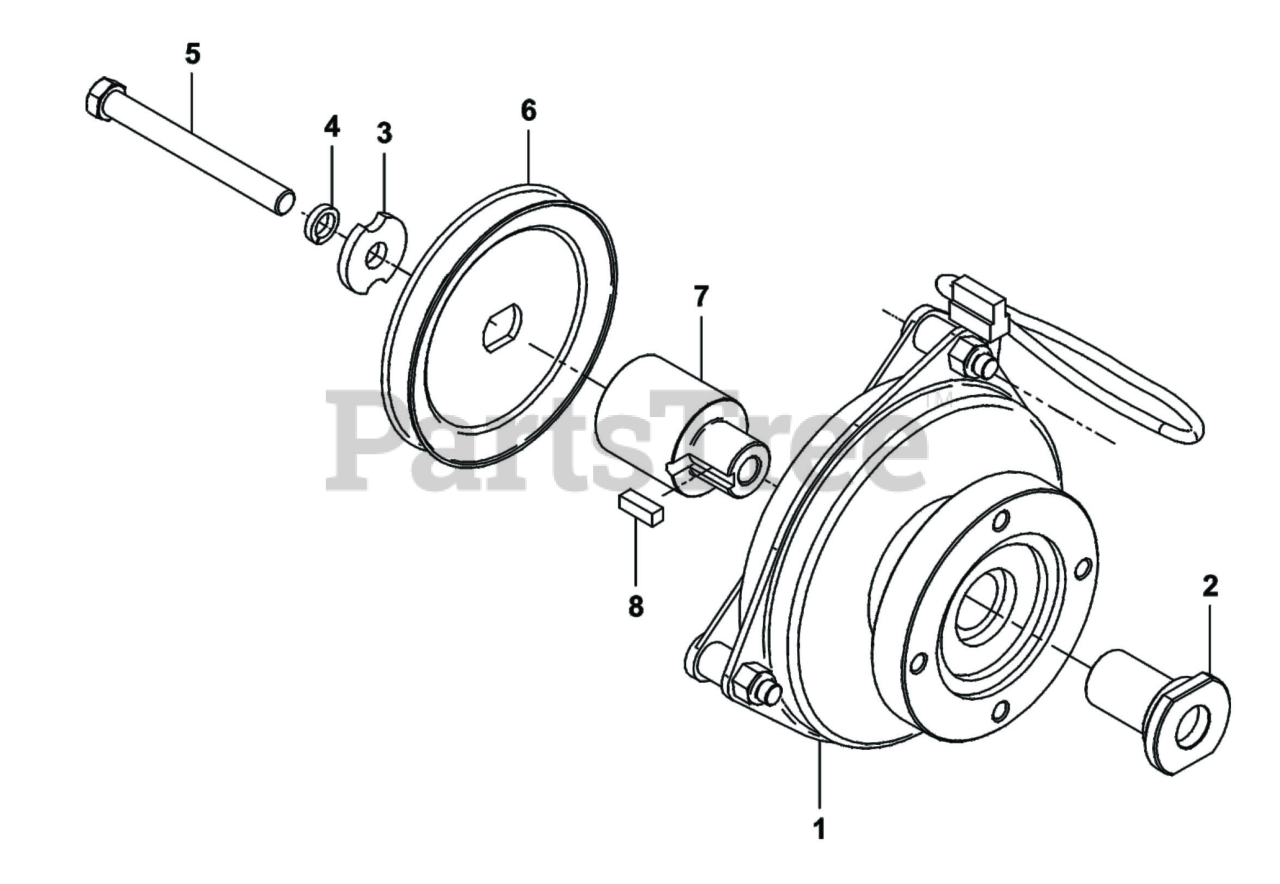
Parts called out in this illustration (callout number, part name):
1	ELECTRIC CLUTCH (110 FT-LBS)
2	CLUTCH SHAFT
3	WASHER-7/16 x 1-3/
4	LOCK WASHER 7/16"
5	SCREW 7/16"-20 X 4"
7	ENGINE PULLEY BUSHING #27
8	KEY, 1/4" X 3/4" LG
